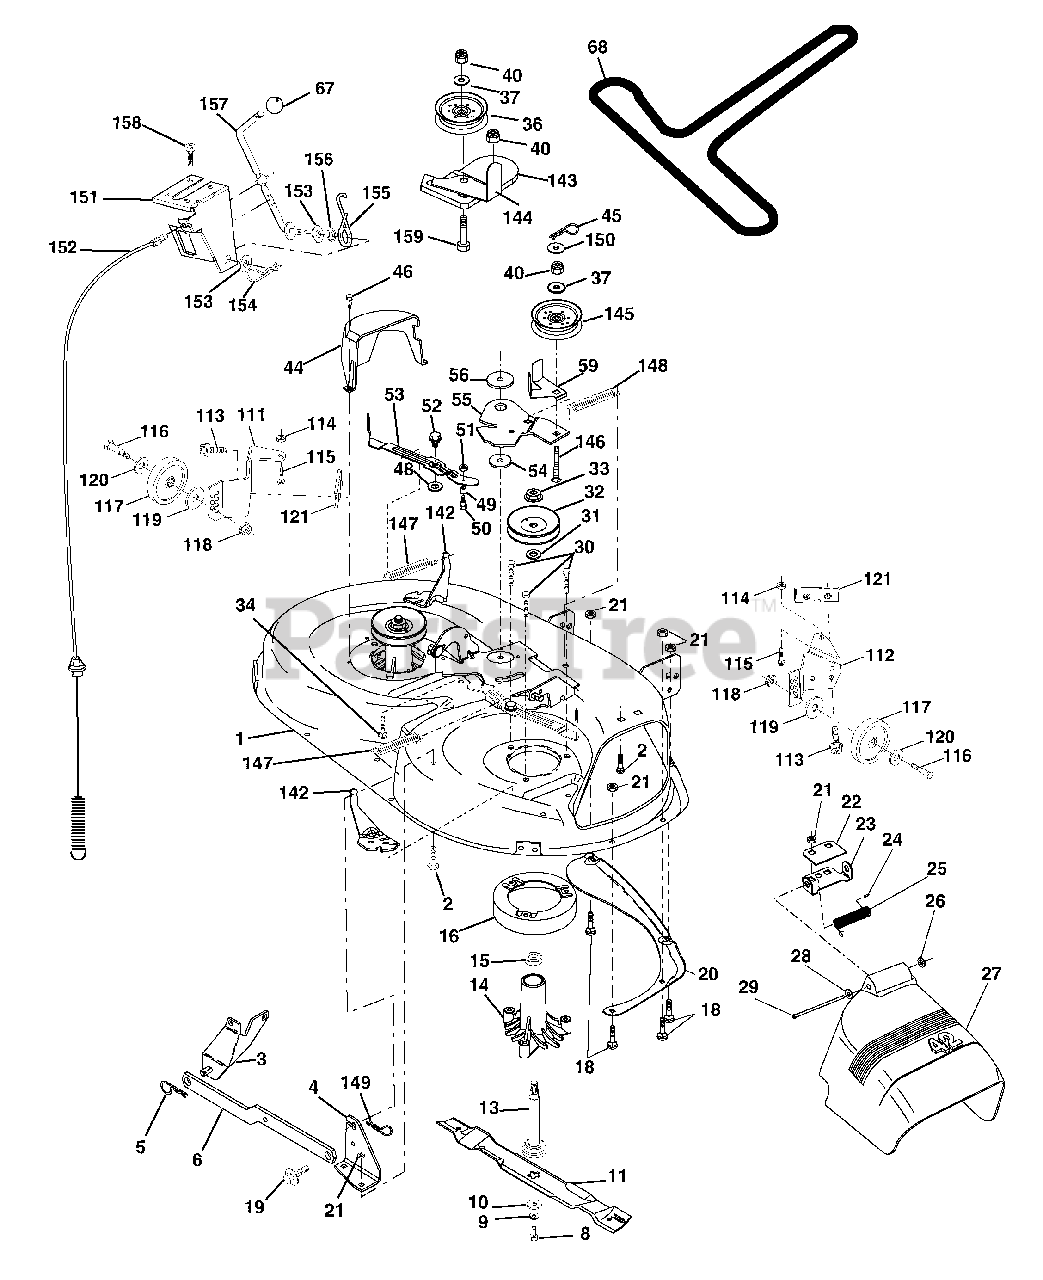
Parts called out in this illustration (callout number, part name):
1	Mower Deck Assembly, 42"
2	Bolt
3	Bracket Asm Fr. Sway Bar 3/42
4	Bracket Asm Deck 42" Sway Bar
5	Retainer Spring
6	Arm, Suspension, Rear
8	Bolt 3/8-24 x 25 Grade 8 patched
9	Washer, Lock
10	Washer,Hardened
11	Blade
13	Shaft Assembly, Mandrel, Vented
14	Housing, Mandrel, Vented
15	Bearing, Ball, Mandrel
16	Stripper, Vented Mower Deck
18	Bolt, Carriage 5/16-18 x 5/8
19	Bolt, Shoulder
20	Baffle, Vortex
21	Nut
22	Stiffener Bracket
23	Bracket, Deflector Mower 42"
24	Cap, Sleeve 80 x 112 Blk Mower
25	Spring, Torsion, Deflector 2 52
26	Nut, Push Phos & Oil
27	Shield, Deflector 42" Blk
28	Washer 11/32 x 5/8 x 16 Gauge
29	Rod, Hinge 42" 6 75 W/G
30	Screw Thdrol Washer Head
31	Washer, Spacer Mower Vented
32	Pulley, Mandrel
33	Nut, Toplock 9/16
34	Bolt
36	Pulley, Idler, Flat
37	Washer 13/32 x 13/16 x 16 Gauge
40	Nut
44	Guard, Mandrel, LH
45	Retainer
46	Screw, Thdrol 1/4-20 x 5/8 T
48	Washer,Hardened
49	Roller Assembly, Cam Follower
50	Bolt, Shoulder #10-24 Grade 5
51	Locknut
52	Bolt, Shoulder 5/16-18 UNC
53	Arm Assembly, Pad, Brake
54	Washer,Hardened
55	Arm, Idler
56	Spacer, Retainer
59	Guard TUV Idler
67	Knob
68	V-Belt, 42" Mower
111	Bracket, Gauge, Wheel LH
112	Bracket, Gauge, Wheel RH
113	Screw Tapping 5/16-18 Unc
114	Nut, Keps 5/16 - 18 UNC
115	Bolt, Carriage 5/16-18 x 1/2
116	Bolt, Shoulder
117	Wheel,Gauge
118	Nut Centerlock 3/8-16
119	Washer 3/8 x 7/8 x 14 Ga.
120	Washer 17/32 x 15/16 x 12 Ga.
121	Bracket, Extruded
142	Arm Spring Brake Mower
143	Bracket Arm Idler 42"
144	Keeper Belt 42" Clutch Cable
145	Pulley Idler Flat
146	Bolt Carriage Idler
147	Spring Extension
148	Spring Return Idler
149	Retainer Spring Yellow
150	Washer 9/32 x 3/4 x 16 Ga.
151	Bracket Clutch Cable
152	Clutch Cable 42"
153	Washer Flat 3/8" Type B
154	Spring Retainer
155	Spring Retention LVR CLTCH CAB
156	Spacer Clutch Cable
157	Rod Clutch Cable 3/8"
158	Screw Hex Thd Cut 1/4-20 x 5/8
159	Bolt Rdhd Sqn 3/8-16 UNC x 1-3/4
